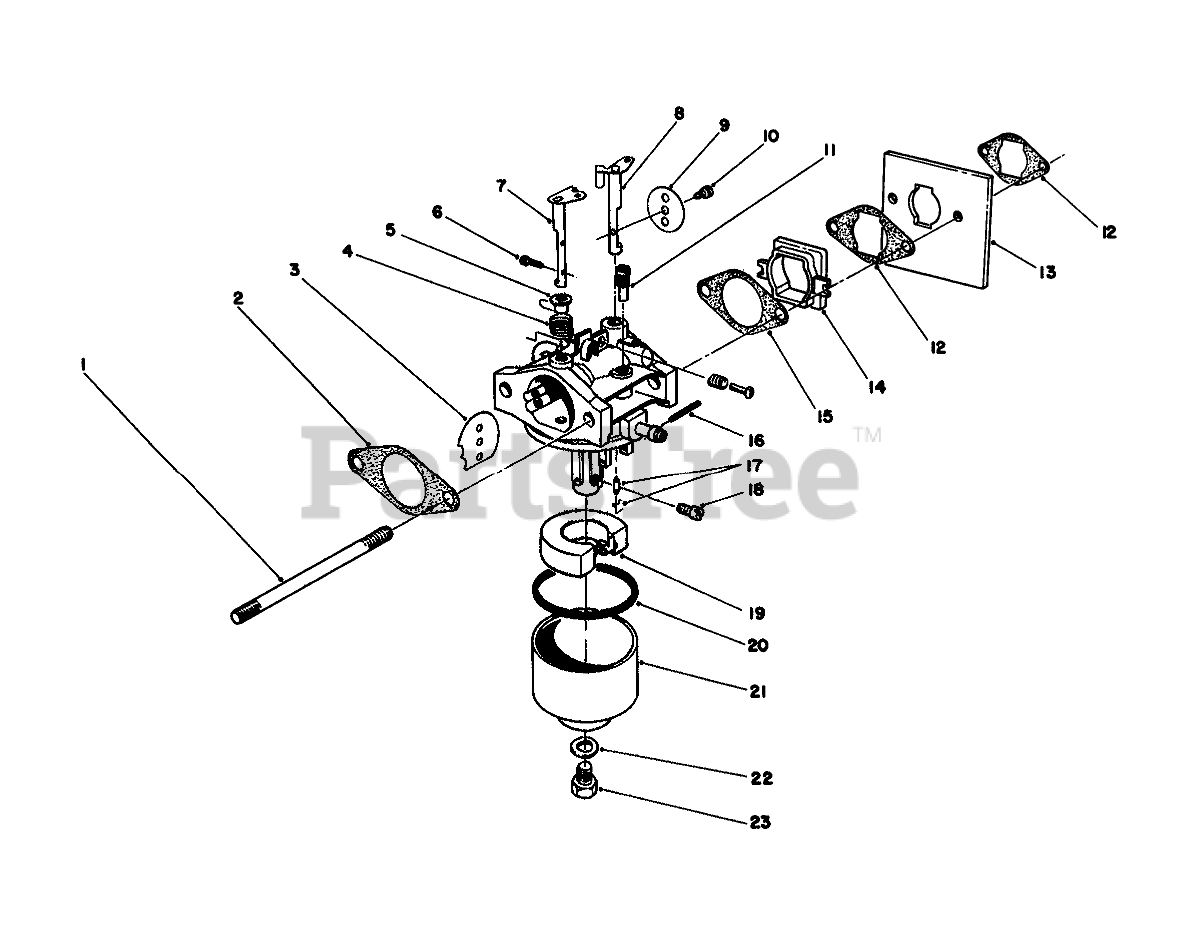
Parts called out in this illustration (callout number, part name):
1	CARB STUD BOLT
2	PLATE
3	PLATE
4	SPRING
5	BUSHING
6	SCREW
7	SHAFT-CHOKE
8	SHAFT
9	PLATE
10	Screw-Throttle
11	PILOT JET
12	GASKET
13	SHIELD
14	INSULATOR
15	GASKET-CARB
16	Pin
17	NEEDLE VALVE ASM
18	MAIN JET (76.3)
19	FLOAT
20	GASKET
21	Bowl-Float
22	GASKET
23	Bolt
